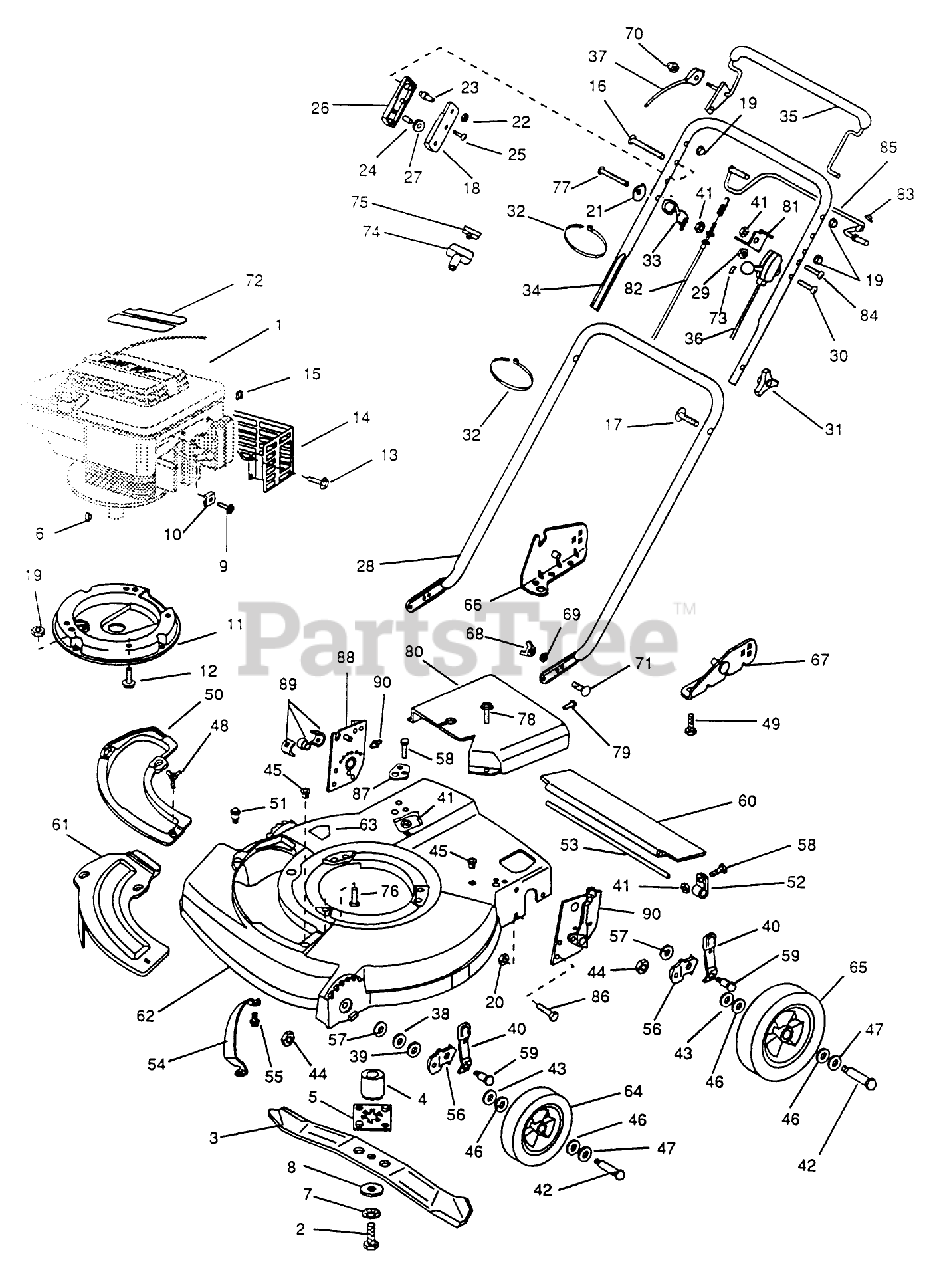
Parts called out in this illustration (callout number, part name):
2	BOLT BLADE QBS
7	LOCKWASHER
8	WASHER
12	SCREW-HWH
15	CLIP-RETAINER, WIRE
20	NUT-LOCK F
21	WASHER-CURVED
22	NUT C/LOCK E
23	COLUMN
24	PIN SKF
25	SCREW
26	OUTER CONTROL CASE
27	PULLEY PL
29	LOCKNUT FLAN
32	TIE-CABLE
35	CONTROL LEVER ARG
36	CABLE AY
37	CABLE AY
38	WASHER
39	WASHER
40	SPRING ARM ASM
41	LOCKNUT E
42	BOLT WHEEL
43	WASHER WROUGHT
44	LOCKNUT
46	WASHER
47	SPACER
48	WING SCREW LAWRE
49	SCREW
52	CLAMP ROD KMC
53	ROD 21" ADVANCE
54	BAR-TOE
57	WASHER
59	BOLT
60	SHIELD-TRAILING
62	HSG AY-SERV-21"*G
62	HOUSING ASM
64	WHEEL & TIRE KIT
68	NUT WING
70	NUT ACORN
75	CLIP-STARTER
76	SCREW V
78	SCREW SEMS TRM HEX HD
81	ANCHOR C'DUIT TRO
82	CABLE - CONTROL
86	SCREW - HEX
87	BOLSTER
88	HEIGHT ADJUSTER AY
89	REAR AXLE BEARING
90	**FITTING LINCOLN
91	HEIGHT ADJUSTER AY
